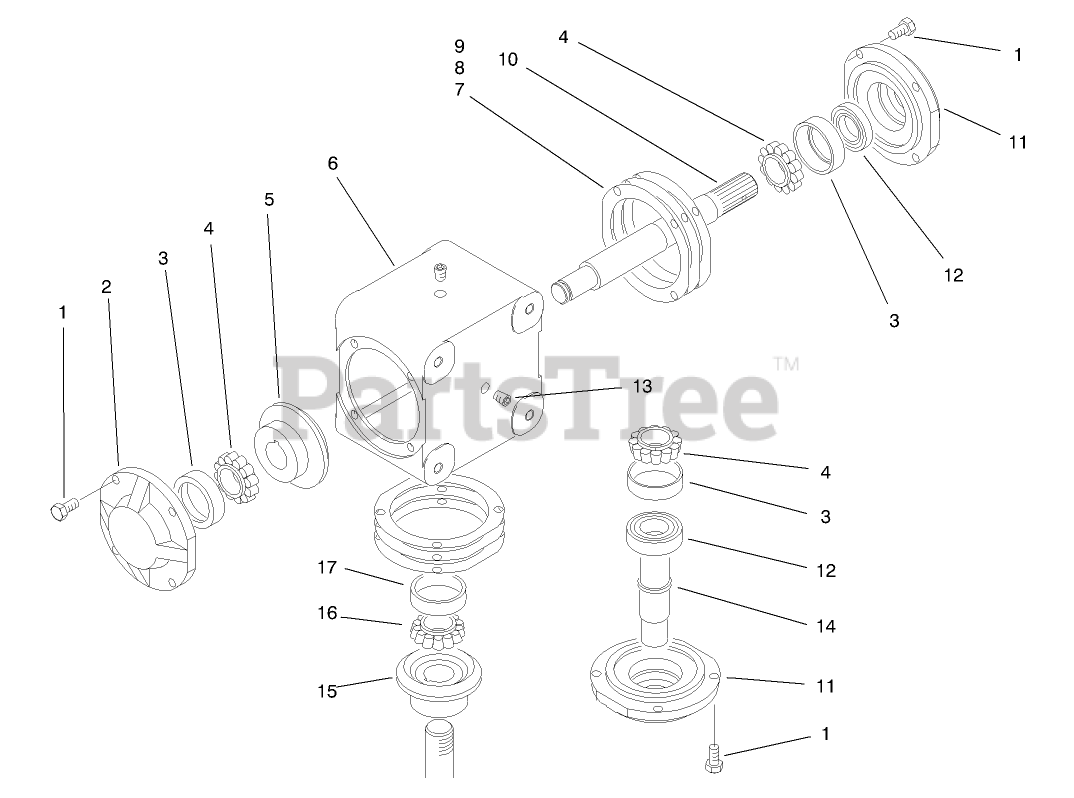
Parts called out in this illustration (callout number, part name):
1	SCREW
3	Cup
4	BEARING - CONE
5	GEAR LH
6	HOUSING
8	GASKET
9	GASKET
10	SHAFT
11	Cap
12	Seal
13	PLUG (OBS, C/R TO 281-10)
14	SHAFT
15	GEAR RH
16	Cone
17	Bearing Cup
